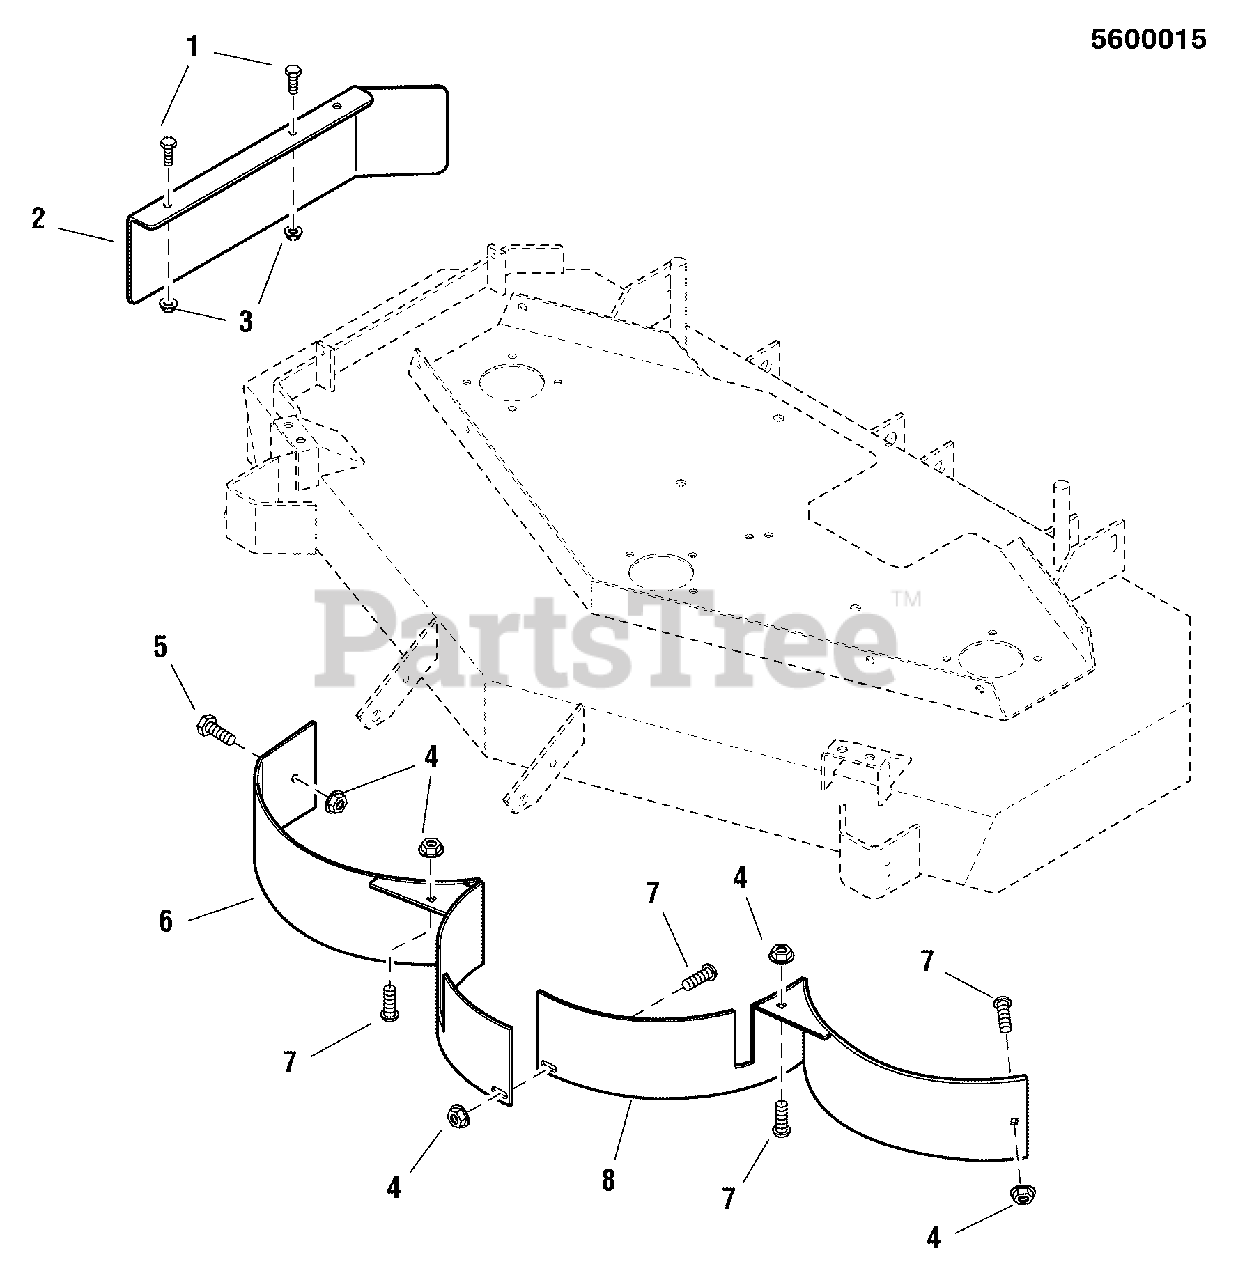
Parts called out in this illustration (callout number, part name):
1	BOLT, 1/4-20 X 3/4, GD5
2	PLATE, Blockoff,
3	NUT, Hex Nylock Flange, 1/4-20
4	NUT, Hex Nylock Flange, 5/16-18
5	BOLT, 5/16-18 X 3/4 GD5
6	PLATE, Mulching, RH
7	BOLT, Carriage, 5/16-18 X 1
8	PLATE, Mulching, LH
